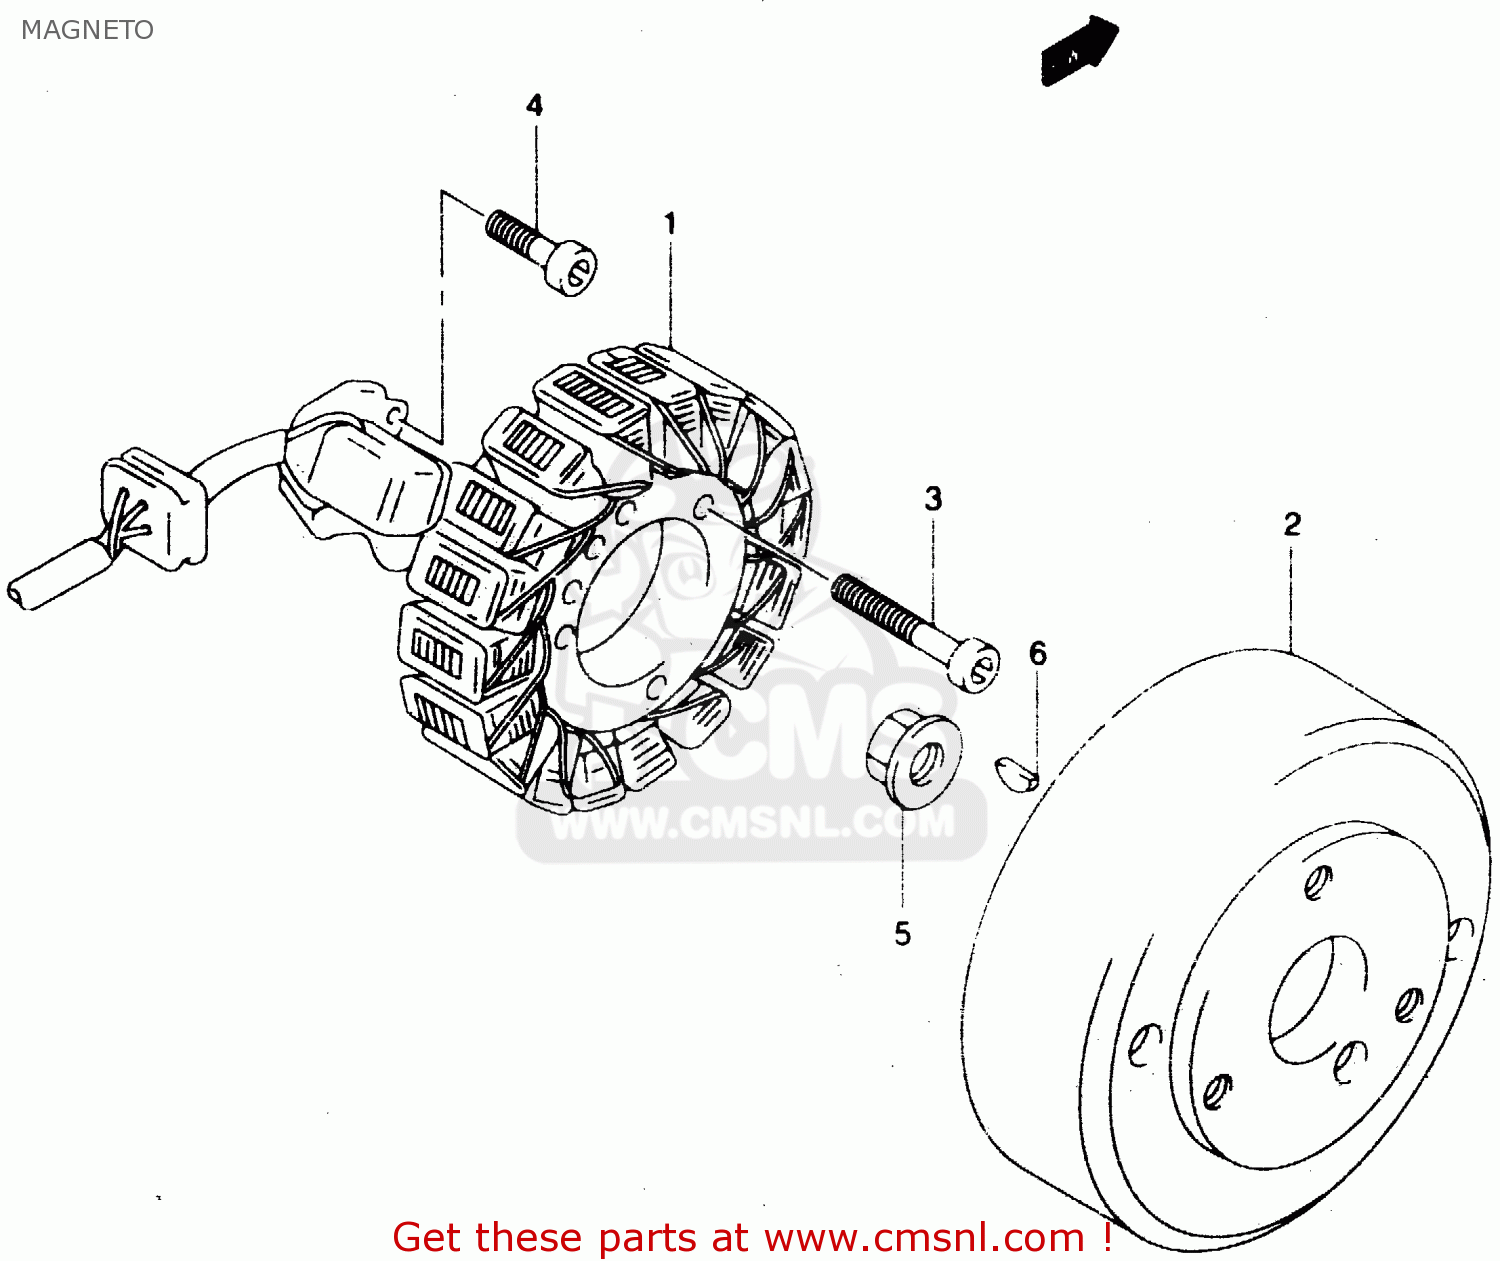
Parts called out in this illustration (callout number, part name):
1	STARTER ASSY
2	ROTOR ASSY
3	BOLT
4	BOLT
5	NUT
6	KEY
